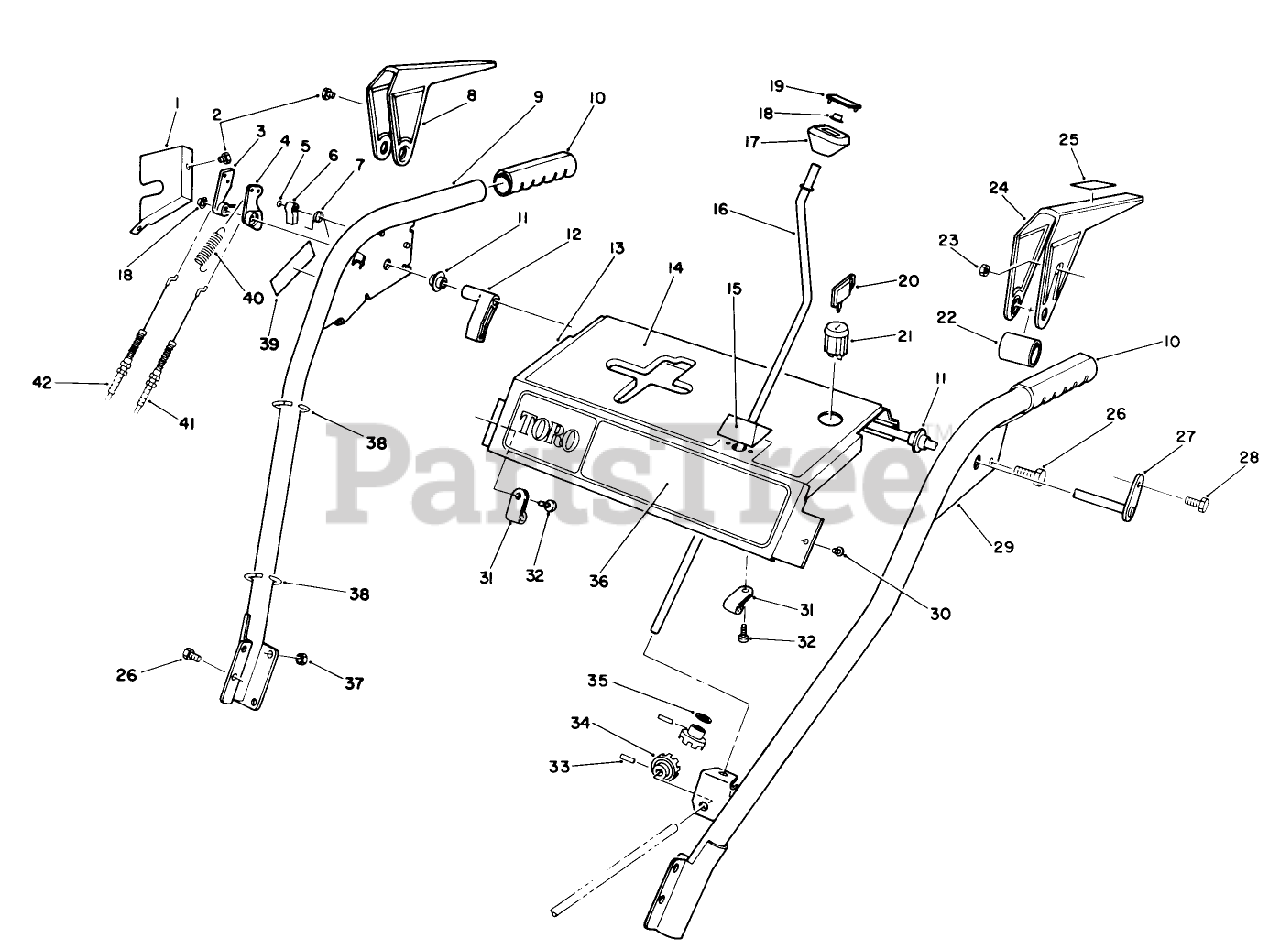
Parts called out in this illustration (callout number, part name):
4	CAM-RELEASE
5	RING-RETAINING
6	LATCH-LOCKING
7	SPRING-TORSION
10	GRIP-HANDLE
11	BUSHING-LEVER
12	LEVER-TRIP
15	PLATE-GUIDE
16	CRANK-ROD, CHUTE
17	KNOB-CONTROL, CHUTE
18	NUT-PUSH
19	COVER-KNOB
20	KEY-IGNITION
21	SWITCH
22	SPACER-LEVER, TRACTION
23	NUT-LOCK, NI
26	SCREW-HHF
27	CROSS ROD ASM
28	SCREW-HWH
30	SCREW-HWHTF
32	SCREW-PPH
33	PIN-SPRING
34	GEAR-UNIVERSAL
35	WASHER-RUBBER
37	NUT-LOCK, NI
38	TIE-CABLE
39	DECAL - ADJ WARNING
41	CABLE-TRACTION
42	CABLE-IMPELLER
